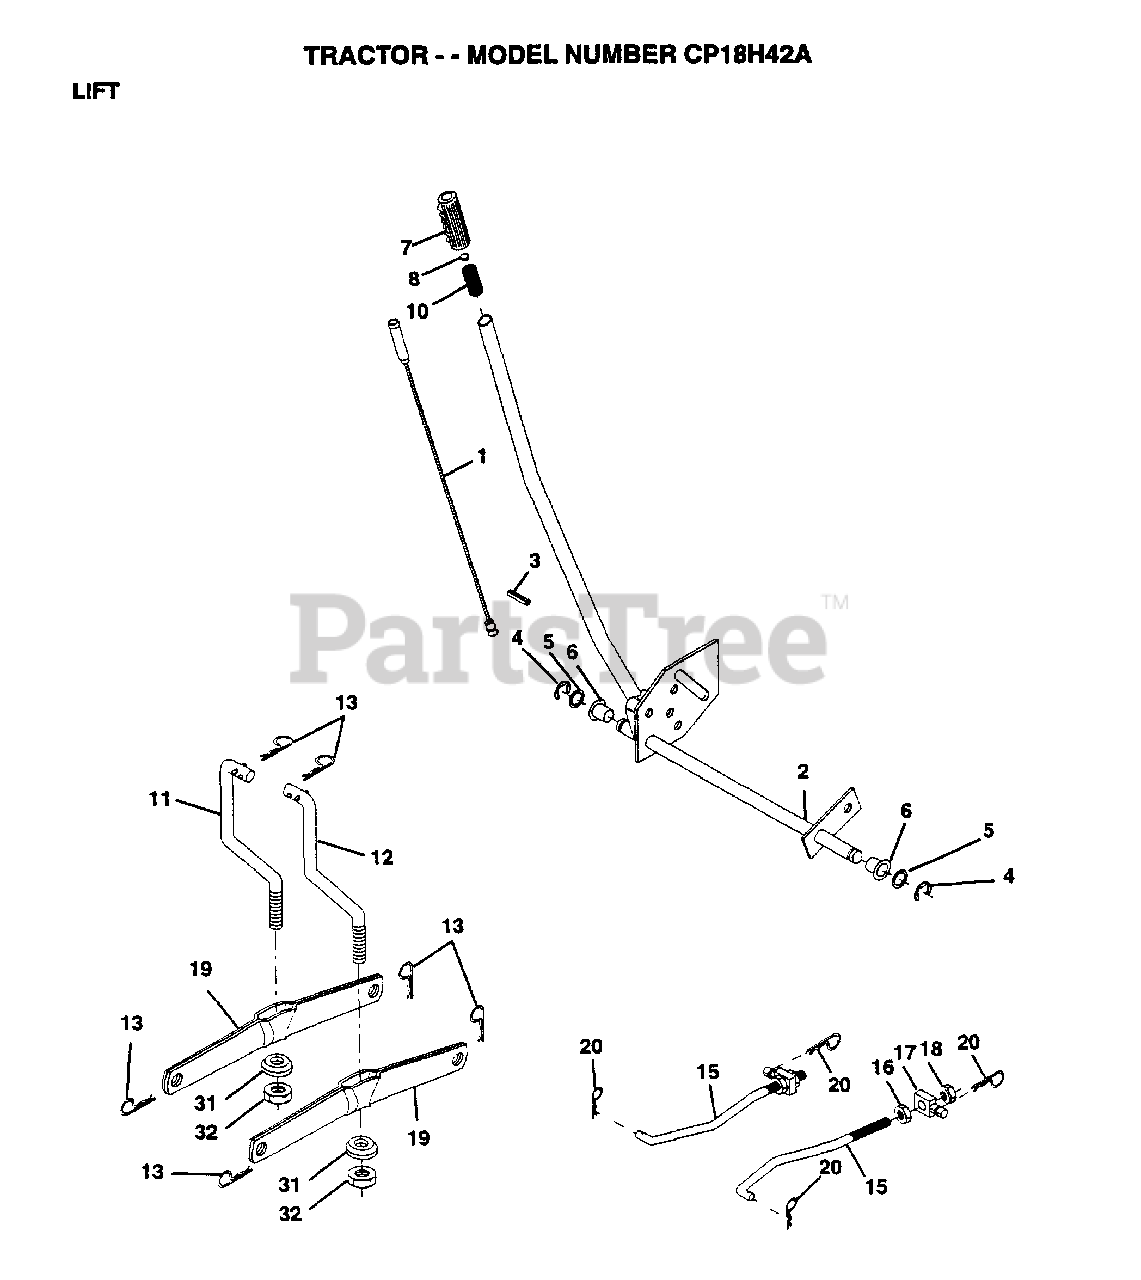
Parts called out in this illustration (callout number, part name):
1	WIRE ASM
2	HANDLE.LIFT.LH.
3	PIN GROOVE
5	WASHER
6	NYLON BEARING
7	GRIP
15	LINK.FRONT
16	NUT
17	TRUNION
18	NUT.LK.W/WSH.1/2.
19	ARM SUSP REAR
20	RETAINER.SPRING
31	BEARING PVT LH
32	NUT.CROWNLOCK.3/8
